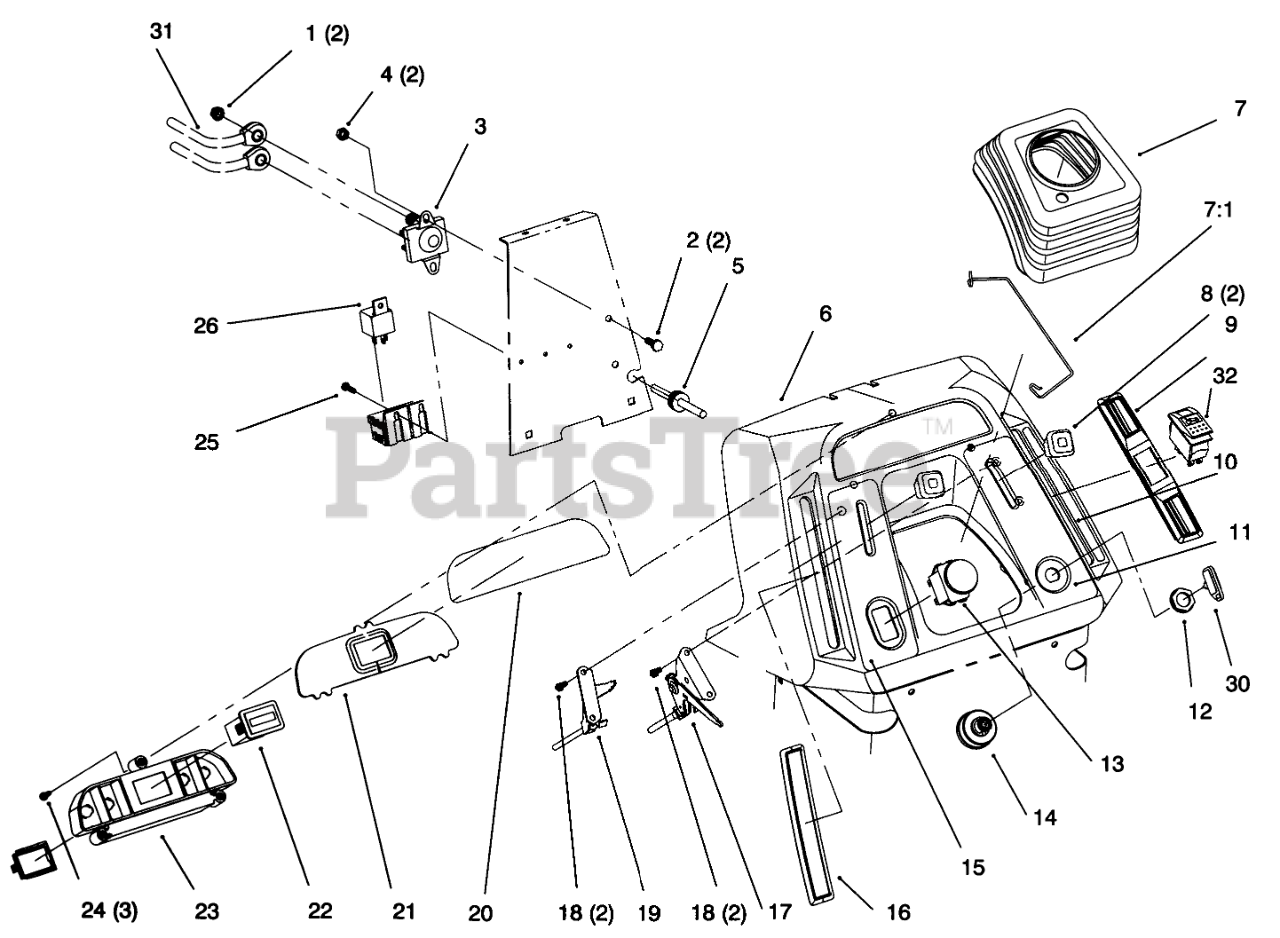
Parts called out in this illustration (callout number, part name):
1	Nut-Hex Lock (Only On: 72042, 72043, 72062, 72063)
2	Screw-HH (Only On: 72042, 72043, 72062, 72063)
3	Solenoid (Only On: 72042, 72043, 72062, 72063)
4	Nut-Lock (Only On: 72042, 72043, 72062, 72063)
5	GROMMET-RUBBER
6	Dash (Only On: 72042, 72062)
6	Dash (Only On: 72043, 72063, 72103)
7	BOOT-STEERING
7:1	CLIP-BOOT
9	Cover-Slot RH (Only On: 72043, 72063)
9	Cover-Cruise (Only On: 72103)
10	Decal-Shift (Only On: 72042, 72062)
11	Decal-Throttle/Ignition (Only On: 72042, 72043)
11	Decal-Throttle/Ignition (Only On: 72062, 72063, 72103)
13	SWITCH-PTO
14	SWITCH-IGNITION
15	Decal-Choke/PTO (Only On: 72042, 72043)
15	Decal-PTO/Choke (Only On: 72062, 72063, 72103)
16	COVER-SLOT, LH
17	Control-Throttle (Only On: 72042, 72043, 72062, 72063)
17	Control-Throttle (Only On: 72103)
19	Control-Choke (Only On: 72042, 72043, 72062, 72063)
19	Control-Choke (Only On: 72103)
20	Decal-Dash Lens (Only On: 72043, 72103)
20	Decal-Dash Lens (Only On: 72042, 72062, 72063)
21	LENS-DASH
22	Hourmeter
23	Light-Indicator (Only On: 72043, 72103)
23	Housing-lndicator Light (Only On: 72042, 72062, 72063)
24	SCREW-PPH
25	Screw-PPH (Only On: 72103)
26	Relay (Only On: 72103)
30	KEY-IGNITION
31	Cable-Battery Red (Only On: 72042, 72043, 72062, 72063)
32	Switch-Cruise (Only On: 72103)
